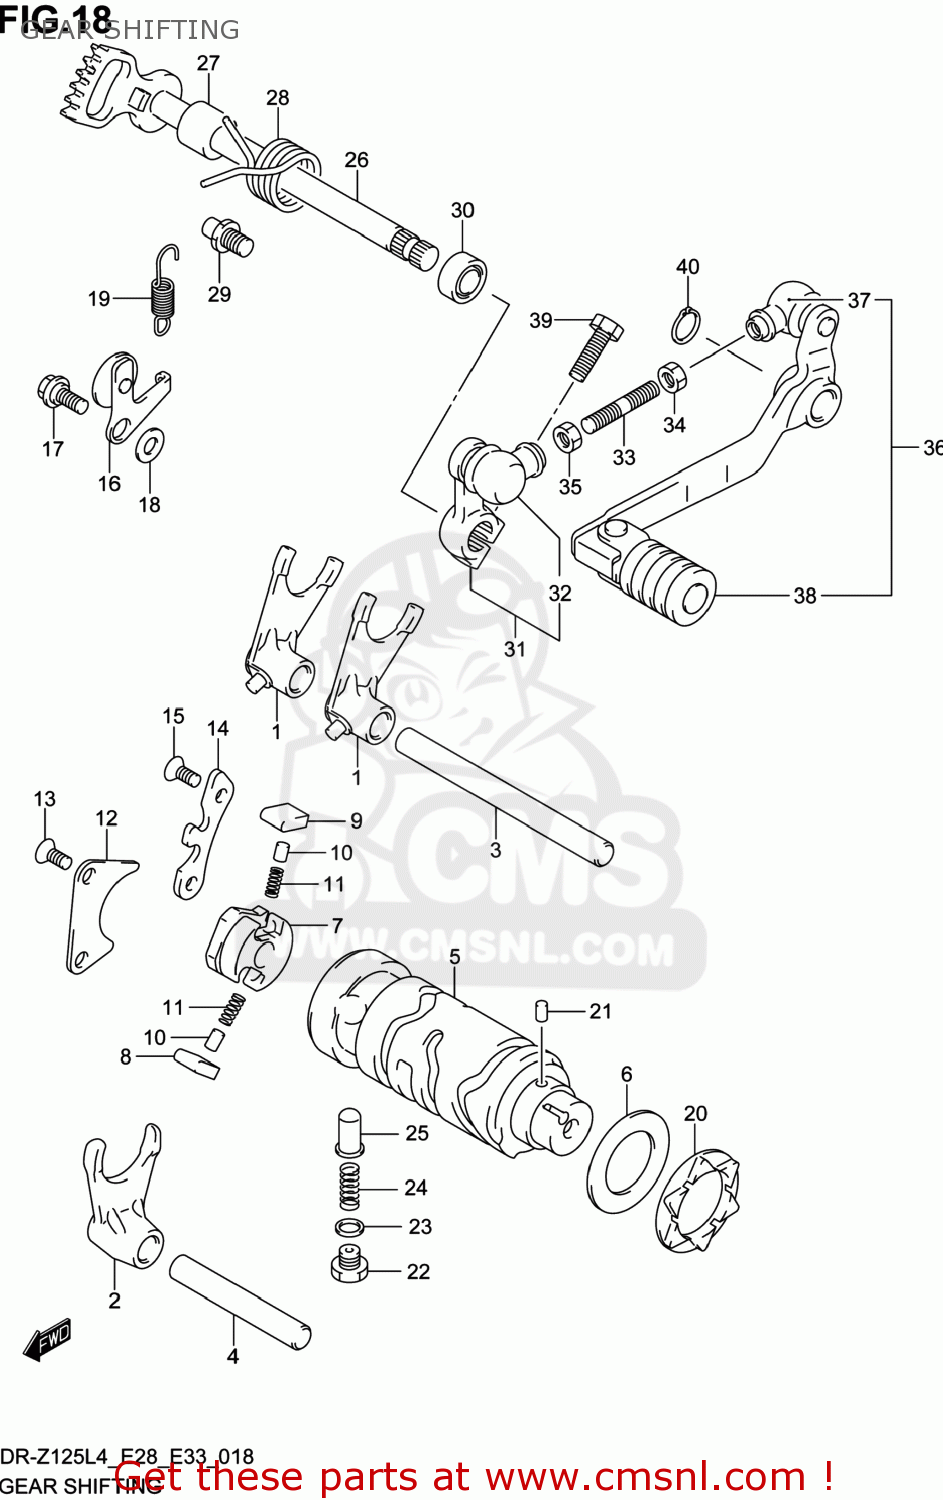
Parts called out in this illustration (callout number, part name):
1	FORK,GEAR SHIFT NO.2
2	FORK,GEAR SHIFT NO.3
3	SHAFT,GEAR SHIFT FORK(L:109)
4	SHAFT,GEAR SHIFT FORK NO.2
5	CAM,GEAR SHIFT
6	SHIM(25X40X1)
7	GEAR,GEAR SHIFT CAM DRIVEN
8	PAWL,GEAR SHIFT NO.1
9	PAWL,GEAR SHIFT NO.2
10	PIN(5X8)
11	SPRING
12	LIFTER,GEAR SHIFT POLE
13	SCREW(6X12)
14	GUIDE,GEAR SHIFT CAM
15	SCREW(6X12)
16	STOPPER,GEAR SHIFT CAM
17	BOLT(6X14.6)
18	WASHER
19	SPRING
20	PLATE,GEAR SHIFT CAM STOPPER
21	PIN
22	PLUG(14X12)
23	GASKET(13.8X18.8X4.8) (NAS)
24	SPRING
25	STOPPER,GEAR SHIFT CAM NO.2
26	SHAFT,GEAR SHIFT
27	SPACER(12X20X15.3)
28	SPRING
29	STOPPER,GEAR SHIFT ARM
30	SEAL,OIL (12X22X9)
31	ARM,GEAR SHIFT LINK
32	COVER,DUST
33	ROD,GEAR SHIFT LINK
34	NUT
35	NUT
36	LEVER ASSY,GEAR SHIFT
37	COVER,DUST
38	RUBBER,GEAR SHIFT PEDAL
39	BOLT
40	CIRCLIP
